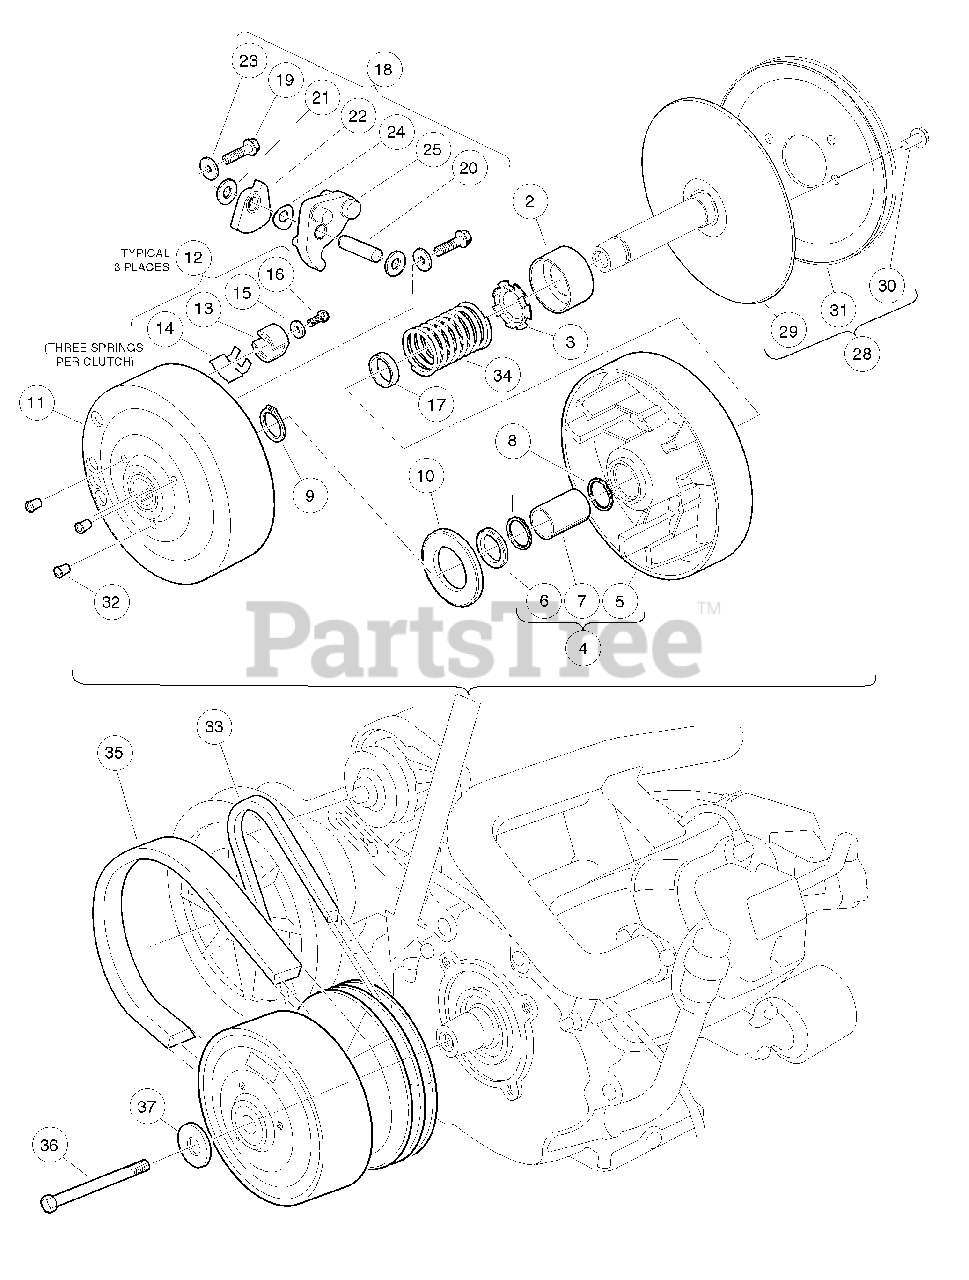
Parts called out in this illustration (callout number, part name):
1	Assembly, Drive Clutch
2	Bearing, Idler
3	Retainer, Spring
4	Movable-Face Assembly
5	Drive Clutch Movable Face
7	Bushing, Split, Drive Clutch
8	Ring, Spiral Backup
9	Ring, 0.810" Internal Retaining
10	Washer, Thrust
11	Drive Hub Assy, Drive Clutch
12	Kit, Drive Clutch Button
13	Driver, Drive Clutch
14	Spring, Drive Button
15	Washer, #10 Type A Flat
16	Screw, #10-24 X 0.50 Hex-Head
17	Spacer, Fixed Face Shaft
18	Kit, Drive Clutch Weight
19	Screw, 1/4-20 X 1.00 Hex Head
20	Pin, 0.3752 X 1.50 Dowel
21	Washer, 0.38" ID Delrin Flat
22	Clutch Weight, Secondary
23	Washer
24	Washer, Wave
25	Weight, Primary
26	Kit, Fixed Face - Drive
28	Fixed Face Drive
29	Fixed Face Assembly, Drive Clutch
30	Screw, 5/16-18 X 0.75 Thread-Forming
31	Pulley, Drive Clutch
32	Cap Plug
34	Spring, Drive Clutch
35	Be It, Drive
36	Screw 3/8-24x5.5 Hex Loc Ptch
37	Washer, 3/8 Type B Flat
